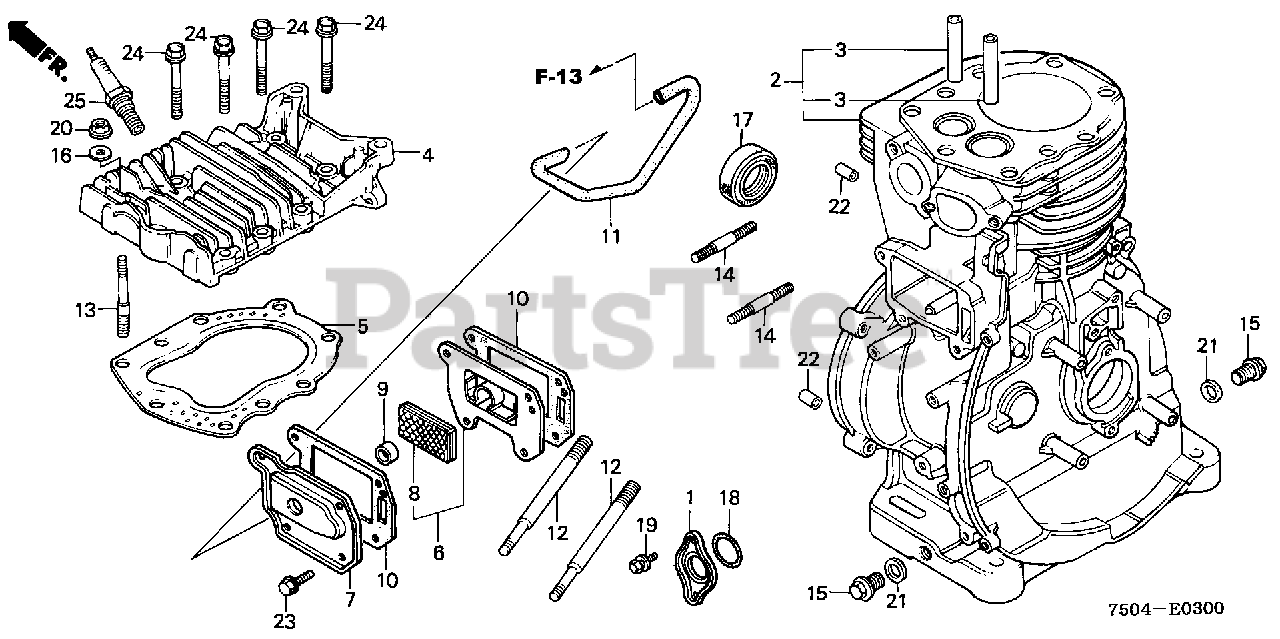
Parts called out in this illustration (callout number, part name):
1	COVER, OIL PAN
3	GUIDE, VALVE
4	CYLINDER HEAD
5	GASKET, CYLINDER HEAD
6	CASE, BREATHER
7	COVER, TAPPET
8	FILTER, BREATHER
9	SEAL, BREATHER
10	GASKET, TAPPET COVER
11	TUBE, BREATHER (NOT AVAILABLE)
12	BOLT, STUD (8X104)
13	BOLT, STUD (10X70)
14	BOLT, STUD (8X35)
15	BOLT, DRAIN PLUG (12X15)
15	BOLT, DRAIN PLUG
16	WASHER, PLAIN (10MM)
17	OIL SEAL (30X46X8)
18	O-RING (27X2.0)
19	BOLT-WASHER (6X12)
20	NUT, FLANGE (10MM)
21	WASHER, DRAIN PLUG (12MM)
22	PIN A, DOWEL (8X14) (YAMADA)
23	BOLT, FLANGE (6X12)
24	BOLT, FLANGE (10X55)
25	SPARK PLUG (BR-4HS) (NGK)
25	SPARK PLUG (W14FR-U) (DENSO)
